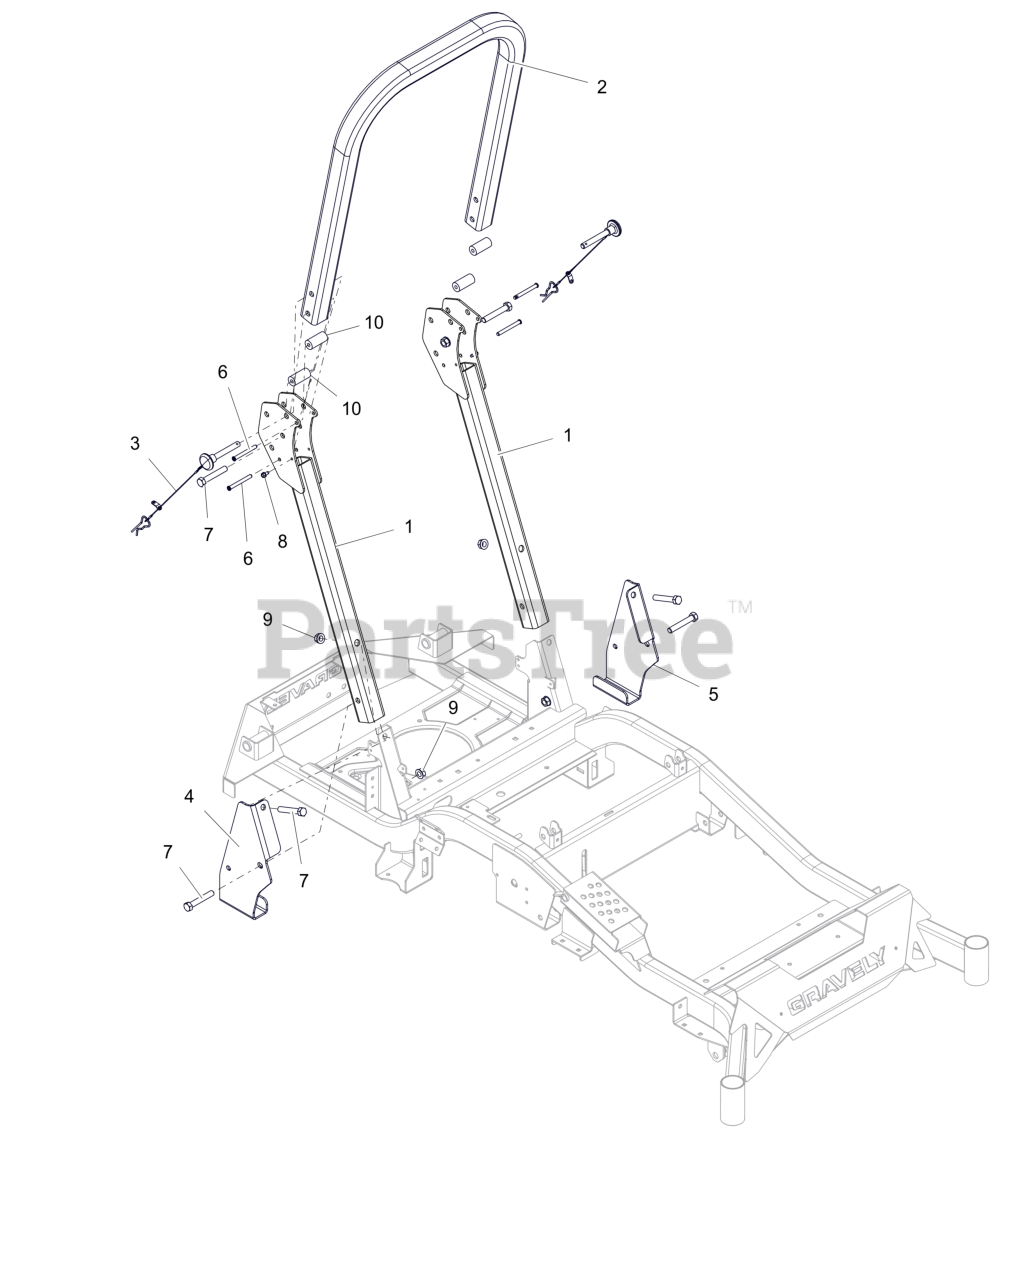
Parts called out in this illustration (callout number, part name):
1	ROPS, REPLACEMENT
2	HOOP, PT Z & ZX ROPS
3	PIN, ROPS W/LANYARD
4	BRKT, ROPS SUPPORT - RH
5	BRKT, ROPS SUPPORT -LH
6	PIN, SLIC .312 X 2.570
7	BLT, HEX .50-13X3.00 G5 ZCC
8	SCR-TAP .25-20X.50 HWH ZCC
9	NUT-LK-CTR-FLG .500-13 GG ZCC
10	BUMPER, ROPS ANTI-VIBRATION
